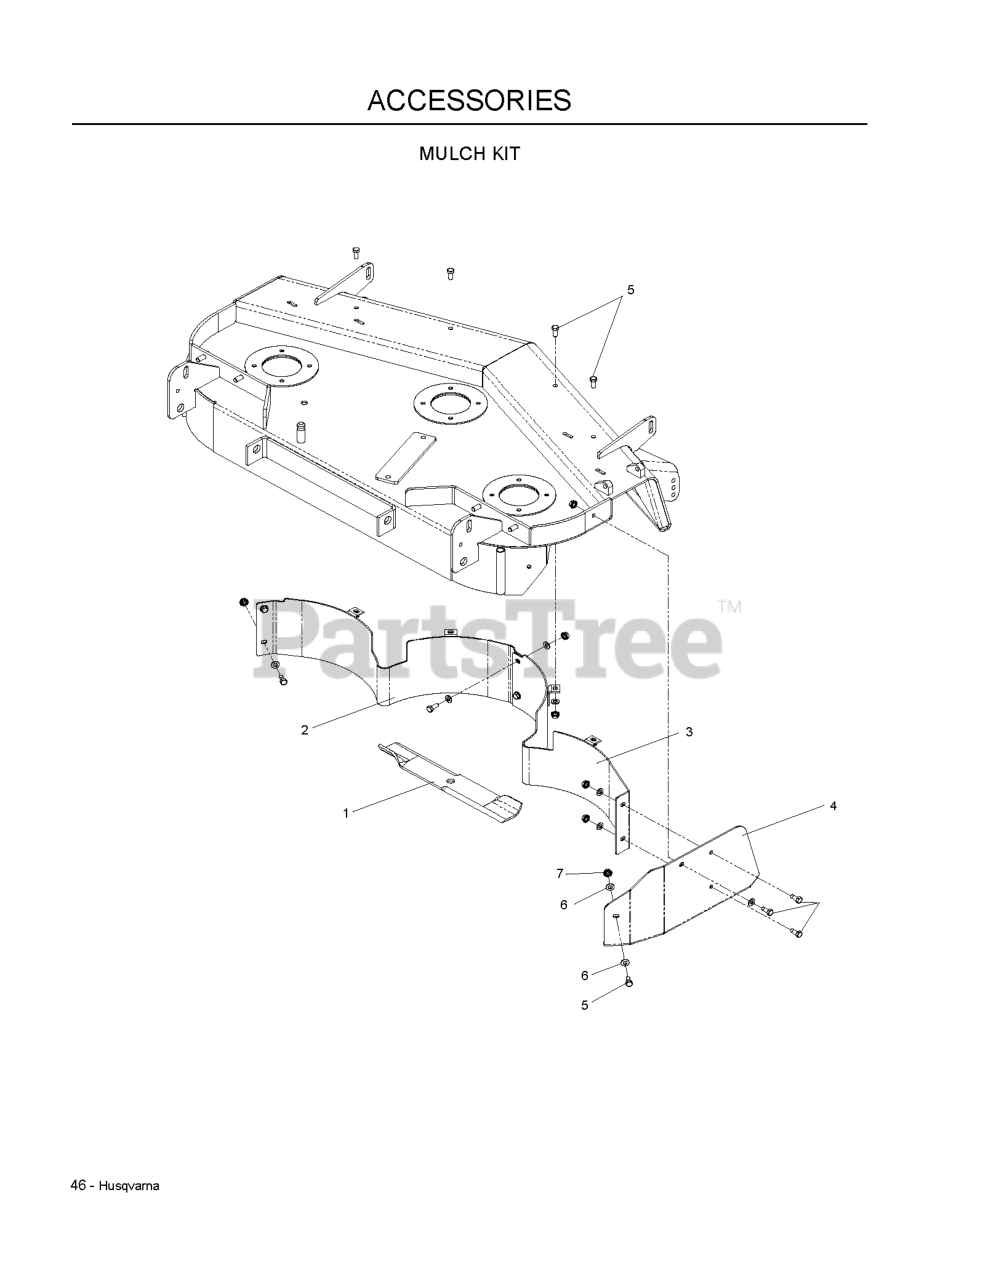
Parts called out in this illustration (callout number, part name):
1	BLADE MULCH 18"
2	BAFFLE WLDMT, 52" L.H.
3	BAFFLE WLDMT, 52" R.H. MULCH
4	MULCH CAP 52
5	HCS 5/16C X 3/4
6	FLAT WASHER 5/16 SAE
7	NUT 5/16C WHIZ
